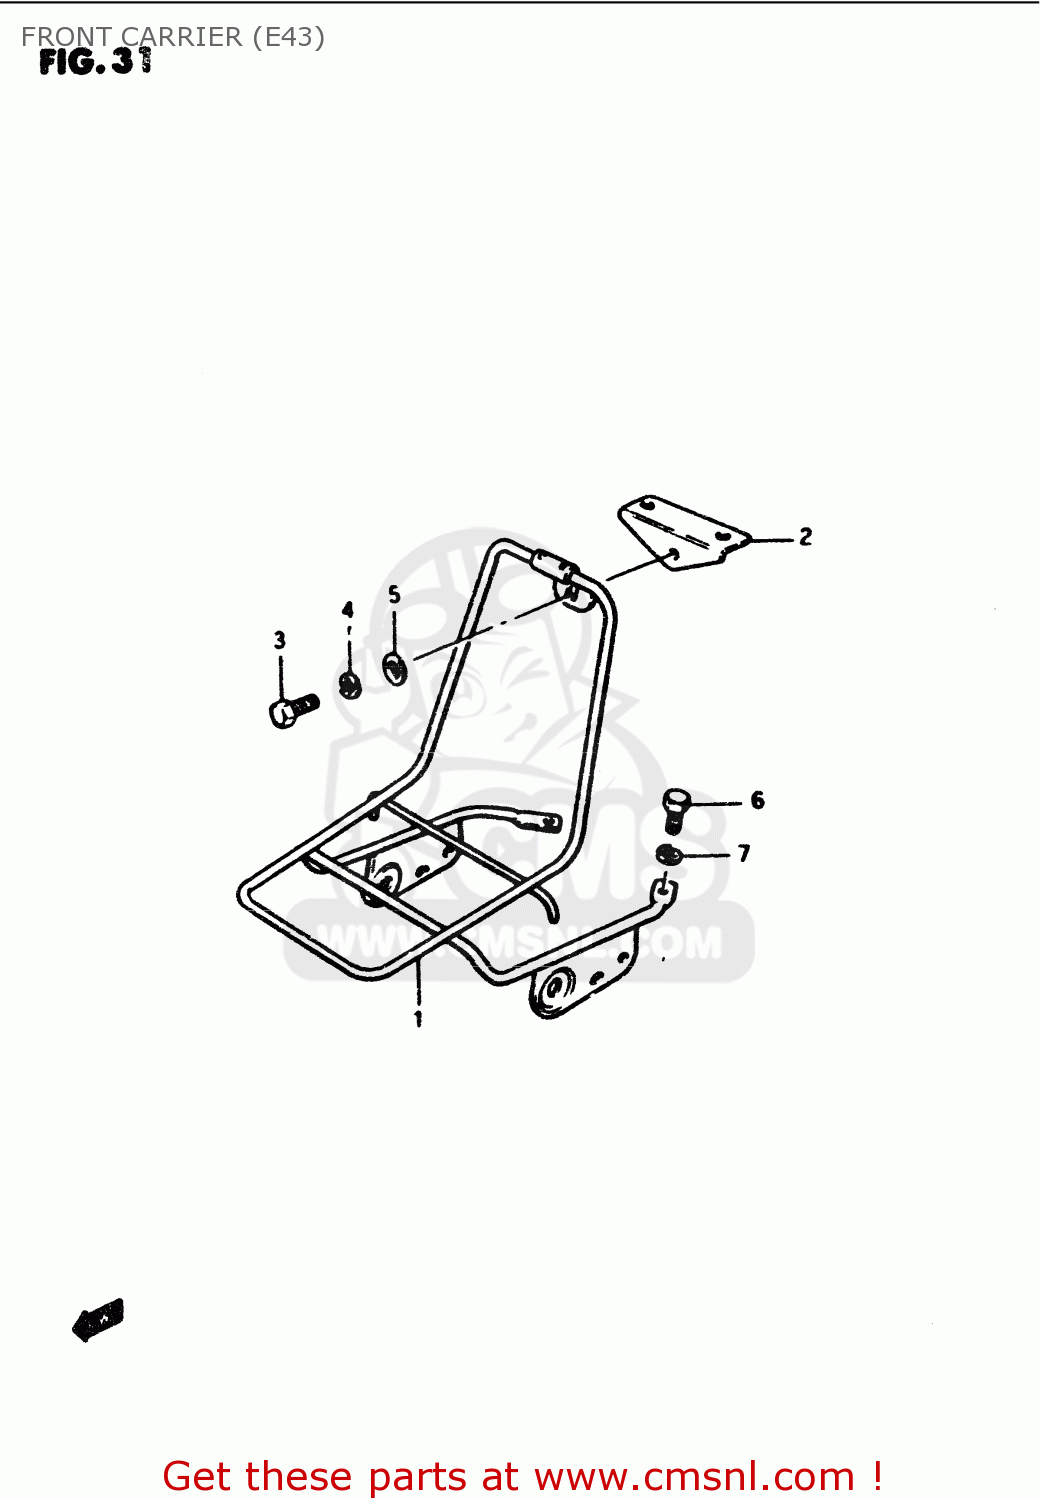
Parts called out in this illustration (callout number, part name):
1	CARRIER, FRONT
2	BRACKET, FRONT CARRIER
3	BOLT
4	WASHER,LOCK
5	WASHER
6	BOLT
7	WASHER,LOCK
